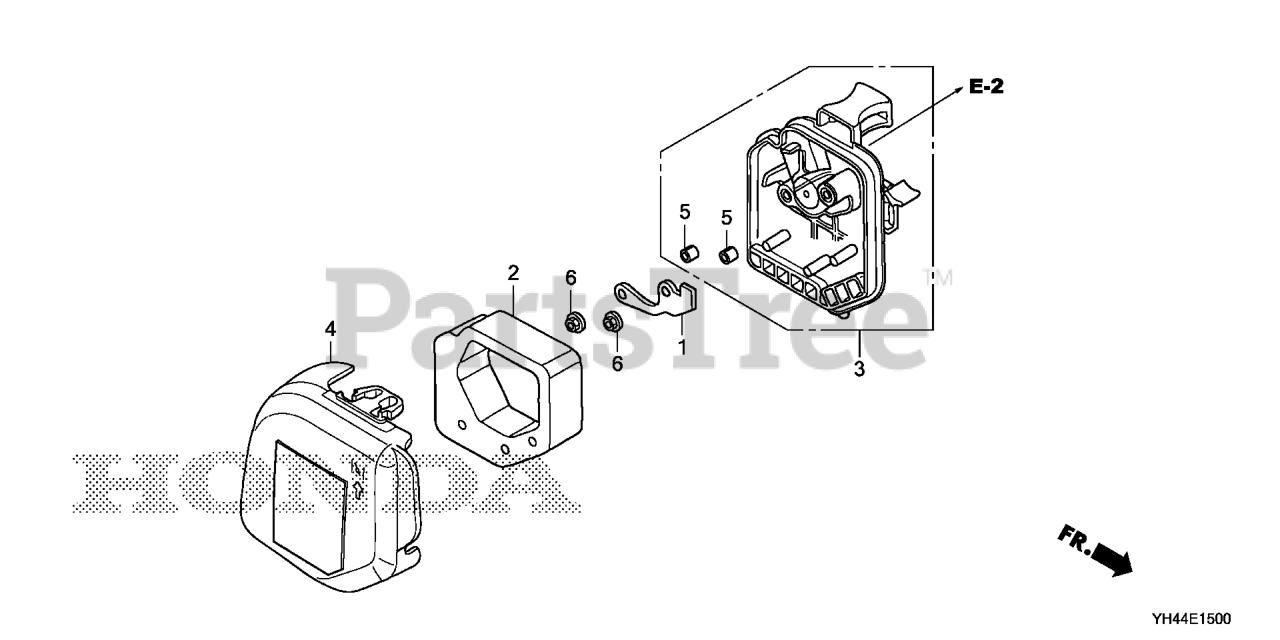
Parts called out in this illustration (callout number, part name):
1	PLATE, OIL TRAP
2	ELEMENT, AIR CLEANER
3	HOUSING, AIR CLEANER
4	COVER, AIR CLEANER
5	COLLAR, AIR CLEANER
6	NUT, FLANGE (5MM)
